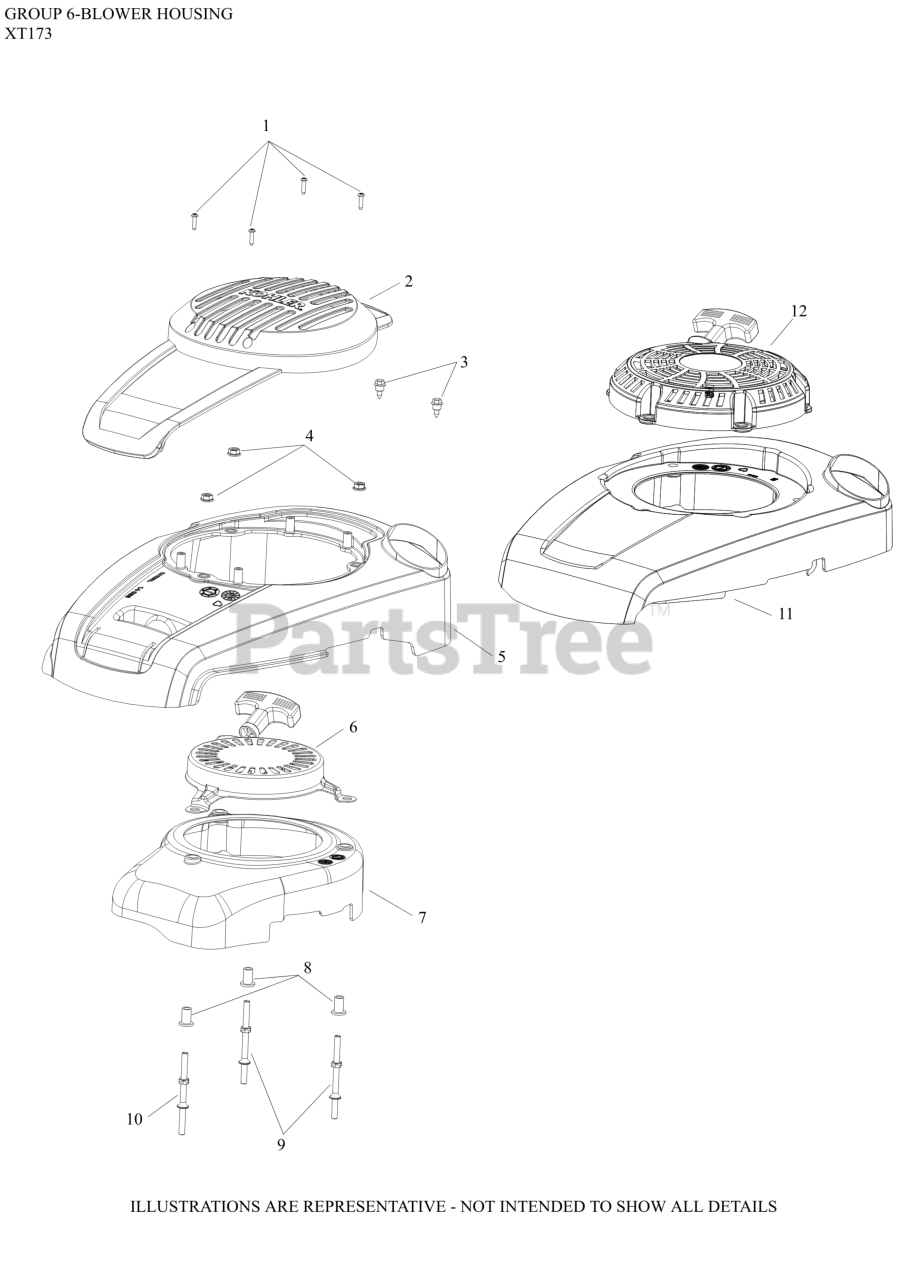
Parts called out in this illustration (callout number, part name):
4	NUT, HEX FLANGE (M6) - USE 14 100 16-S
9	STUD-USE 14 072 26-S
10	STUD-USE 14 072 25-S
11	COVER, ENGINE
